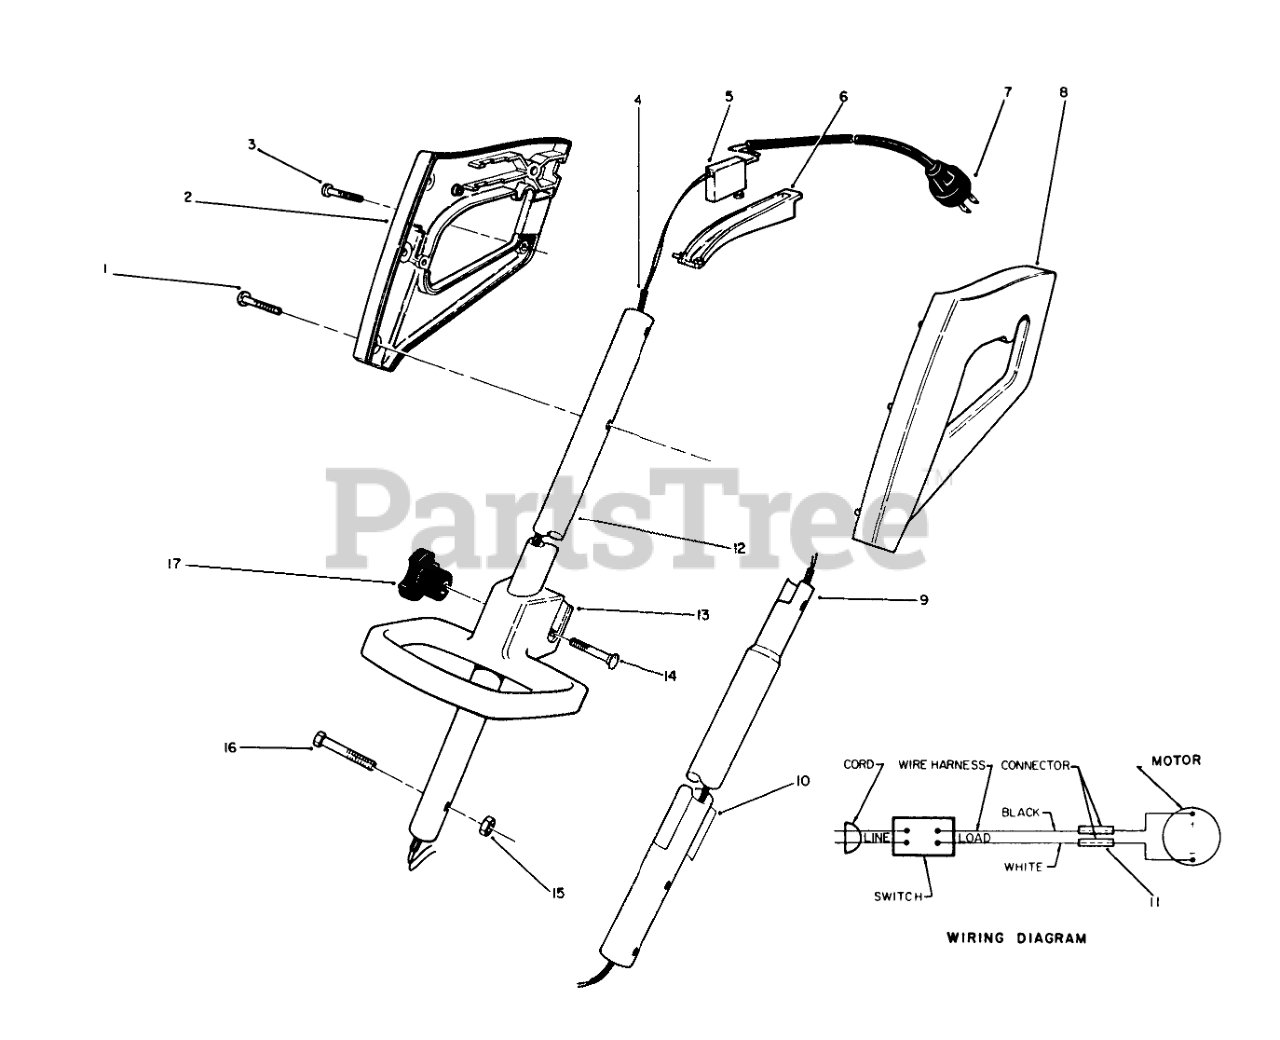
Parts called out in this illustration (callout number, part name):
1	Screw
2	Grip-Hand R.H.
3	SCREW-PPH
4	WIRE HARNESS
5	SWITCH
6	Bar Switch
7	Cord-Power
8	Grip-Hand L.H.
9	TUBE-LOWER
10	CONNECTOR WIRE JOINT
11	TUBE-UPPER
12	Handle
13	BOLT-CARR
14	NUT-LOCK, NI
15	HEX HD MACHINE SCREW
16	Knob
17	REP. SERIAL PLT
